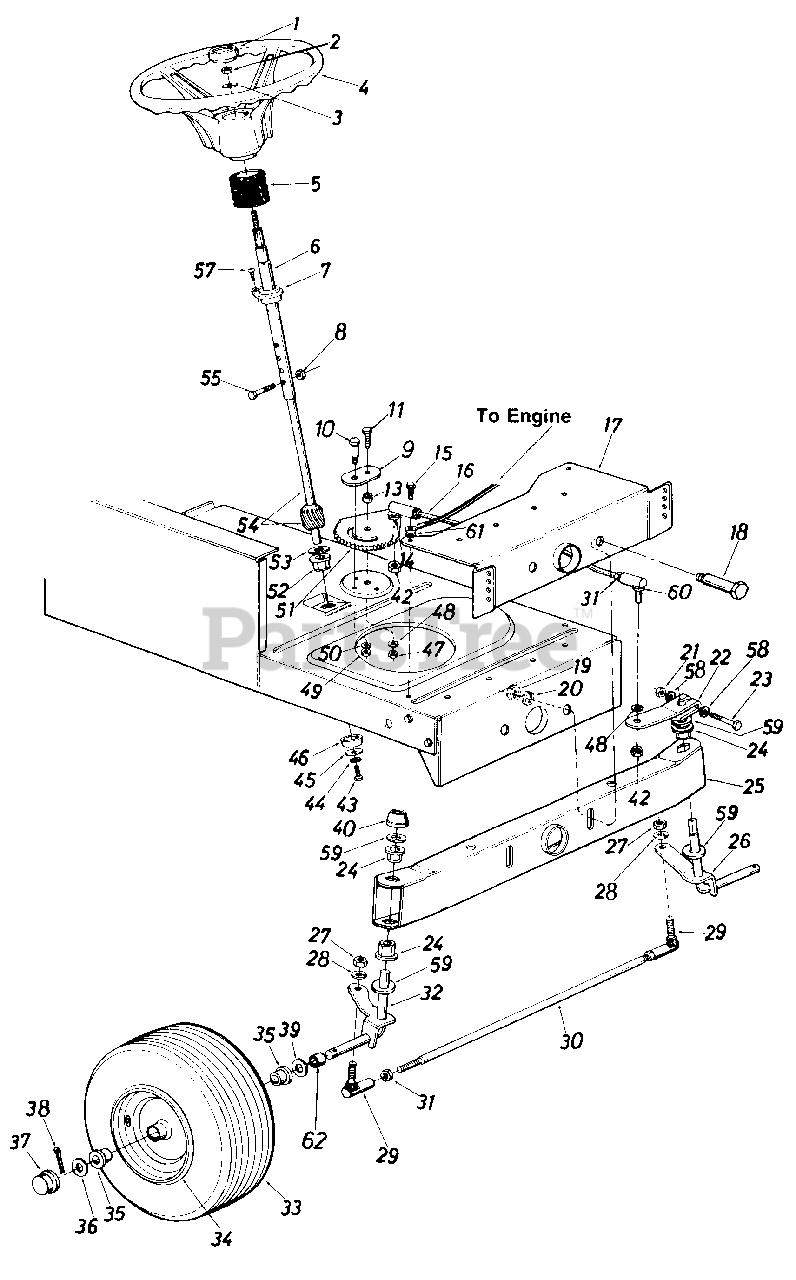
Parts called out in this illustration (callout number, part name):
1	Steering Wheel Cap
2	Hex L-Nut 5/16-24 Thd.
3	Belleville Wash. .345" I.D.
4	Steering Wheel
5	Steering Bellow
6	Steering Column Ass'y.
7	Flange Bearing .890 I.D. x 1.36 O.D.
8	Hex L-Nut 1/4-20 Thd.
9	Retainer Plate
10	Shoulder Bolt .437" Dia. x .35 Lg. 5/16-18 Thd.
11	Hex Bolt 3/8-24 x 1.0" Lg. (Grade 5)
13	Spacer .380" I.D. x .625" O.D.
14	L-Wash. 3/8" I.D.
15	Hex Wash. Hd. Self-Tap Scr.
16	Steering Drag Link
17	Front Pivot Brkt.
18	Shoulder Bolt .498" Dia. x 2.04 Lg. 3/8-16 Thd.
19	Hex Nut 3/8-16 Thd.
20	L-Wash. 3/8" I.D.
21	Hex Cent. L-Nut 5/16-24 Thd.
22	Steering Arm Front Axle
23	Hex Bolt 5/16-24 x 2.00" Lg. (Grade 5)
24	Hex Flg. Brg. .634 I.D.
26	Front Axle Ass'y. L.H.
27	H:ex Nut 3/8-24 Thd.
28	L-Wash. 3/8" I.D.
29	Ball Joint 3/8-24 Thd.
30	Tie Rod
31	Hex Jam Nut 3/8-24 Thd.
32	Front Axle Ass'y. R.H.
33	Wheel Ass'y. Comp.
34	Front Wheel Rim Only
35	Needle Bearing
36	Fl-Wash. .635" I.D. x 1.59" O.D.
37	Front Wheel Hub Cap
38	Cotter Pin 1/8" Dia. x 1.25" Lg.
39	Fl-Wash. .640" I.D. x 1.24" O.D.
40	Spring Roll Pin
42	Hex Jam Nut 3/8-24 Thd.
43	Hex L-Bolt 5/16-18 x .62"
44	L-Wash. 5/16" I.D.
45	Fl-Wash. .33" I.D. x 1.25" O.D.
46	Spacer (Plastic)
47	Hex Nut 3/8-24 Thd.
48	L-Wash. 3/8" I.D.
49	Hex Nut 5/16-18 Thd.
50	L-Wash. 5/16" I.D.
51	Steering Gear Segment
52	Hex Flg. Brg. .634 I.D.
53	Fl-Wash. (Hardened)
54	Steering Shaft Lower
55	Hex Bolt 1/4-20 x 1.31" Lg.
57	Oval Hd. Cr. Sunk Scr. #10 x 5/8" Lg.
58	Wave Wash. .32" I.D. x .62"
59	Fl-Wash. (Hardened)
60	Drag Link Ball Joint 3/8-24 Thd.
61	Ext. L-Wash. 5/16" I.D.
62	Spacer.635
